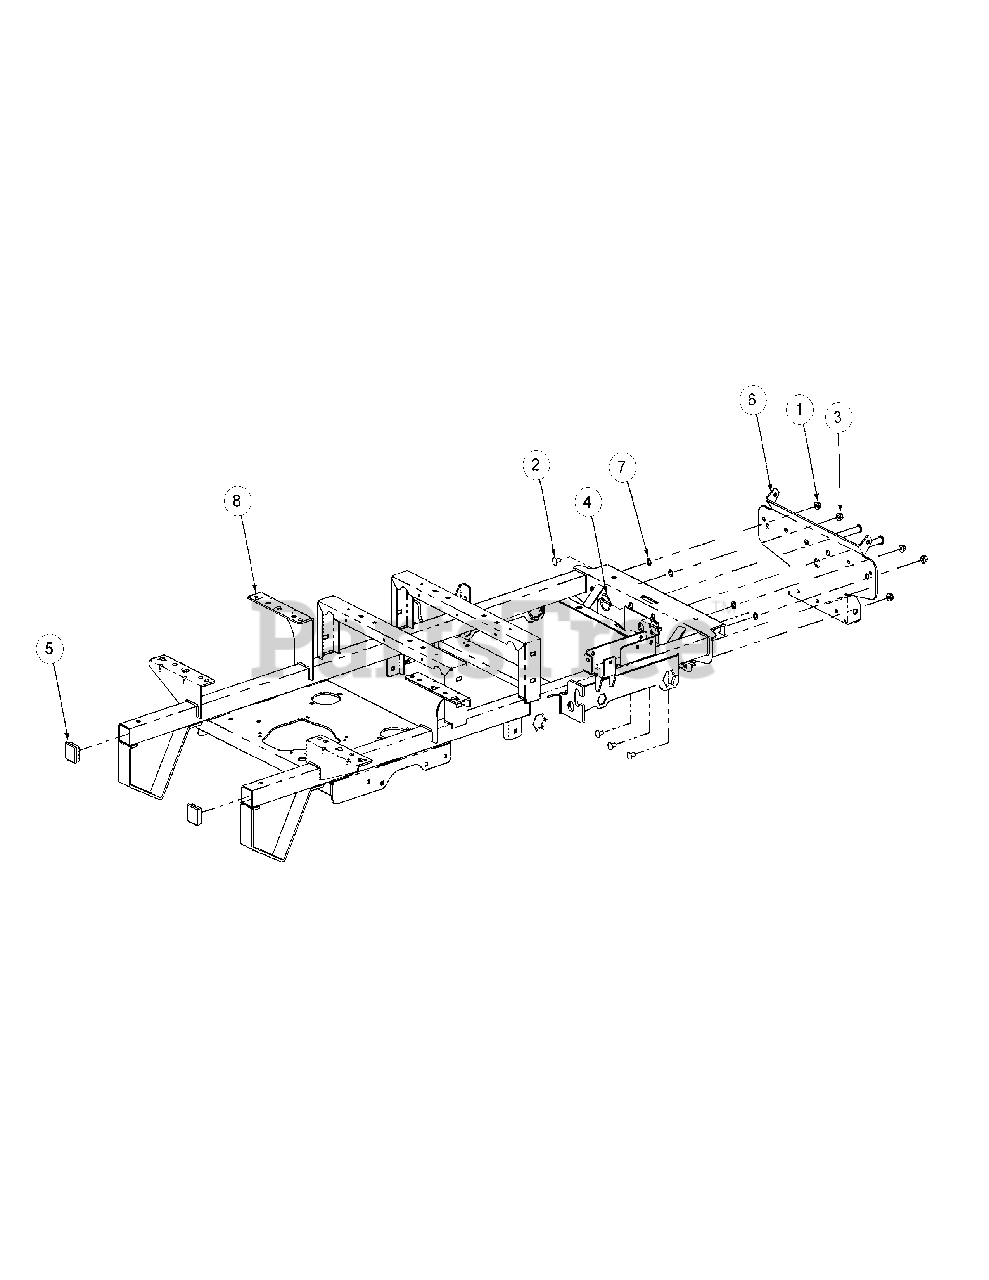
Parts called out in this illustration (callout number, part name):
1	Hex Nut, 3/8-16 Flange Lock
2	Carriage Bolt, 3/8-16 x .75 Long
3	Clevis Pin, .625 Dia x 4.375 Long
4	Linch Pin, 3/16 Dia.
5	Plug, Square Tube
6	Bracket Assembly, Frame, Front
7	Push Retainer, 3/8"-Thread Stud
8	Frame Assembly
